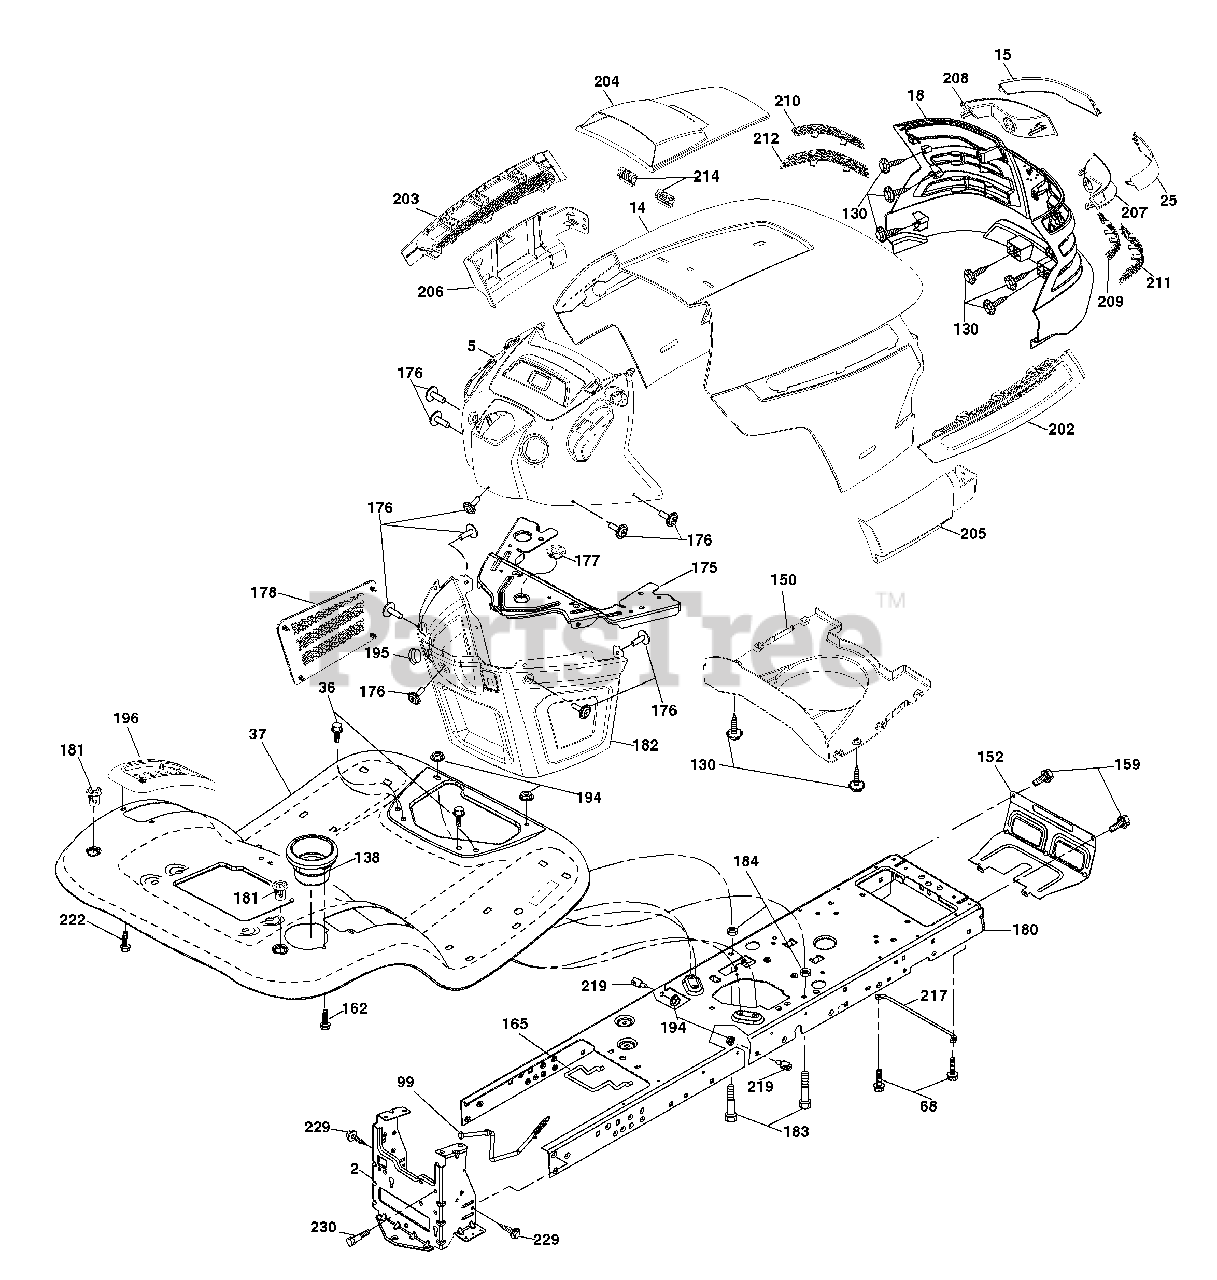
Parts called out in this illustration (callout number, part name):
14	Hood
18	Grille/Lens Asm.
36	Screw 5/16-18 x 3/4
37	Fender
68	Screw Thdrol 5/16-18 x 1/2
99	Rod Asm Bypass
130	Screw 10 x 3/4 Single Lead-Hex
138	Cupholder
152	Shield Browning
159	Screw 3/8-16 x 3/4
165	Support Tank Rear
175	Crossmember
176	Screw 10-24 x 5/8
177	Bushing Steering
178	Cargo Net Asm.
180	Chassis
181	Bushing Mtg. Fender Crgo
182	Dash Lower
183	Bolt Fin Hex 5/16-18 unc x 1-1/4
184	Spacer Fender
194	Nut Lock Hex Flange 5/16-18
195	Plug Hole Dash Lower
196	Console Asm. Deck Lift
202	Vent Side Hood RH
203	Vent Side Hood LH
204	Vent Top Hood
205	Skirt Hood Side RH
206	Skirt Hood Side LH
209	Insert Hex Top RH
210	Insert Hex Top Lh
211	Insert Hex Bottom RH
212	Insert Hex Bottom LH
214	Clip Retainer Tinner
217	Rod Pivot
219	Stud Fastner
222	Screw Thdrol 1/4-20 x 5/8
229	Screw Hexwsh Thdr 3/8-16 x 3/4
230	Bolt Shoulder 5/16-18
